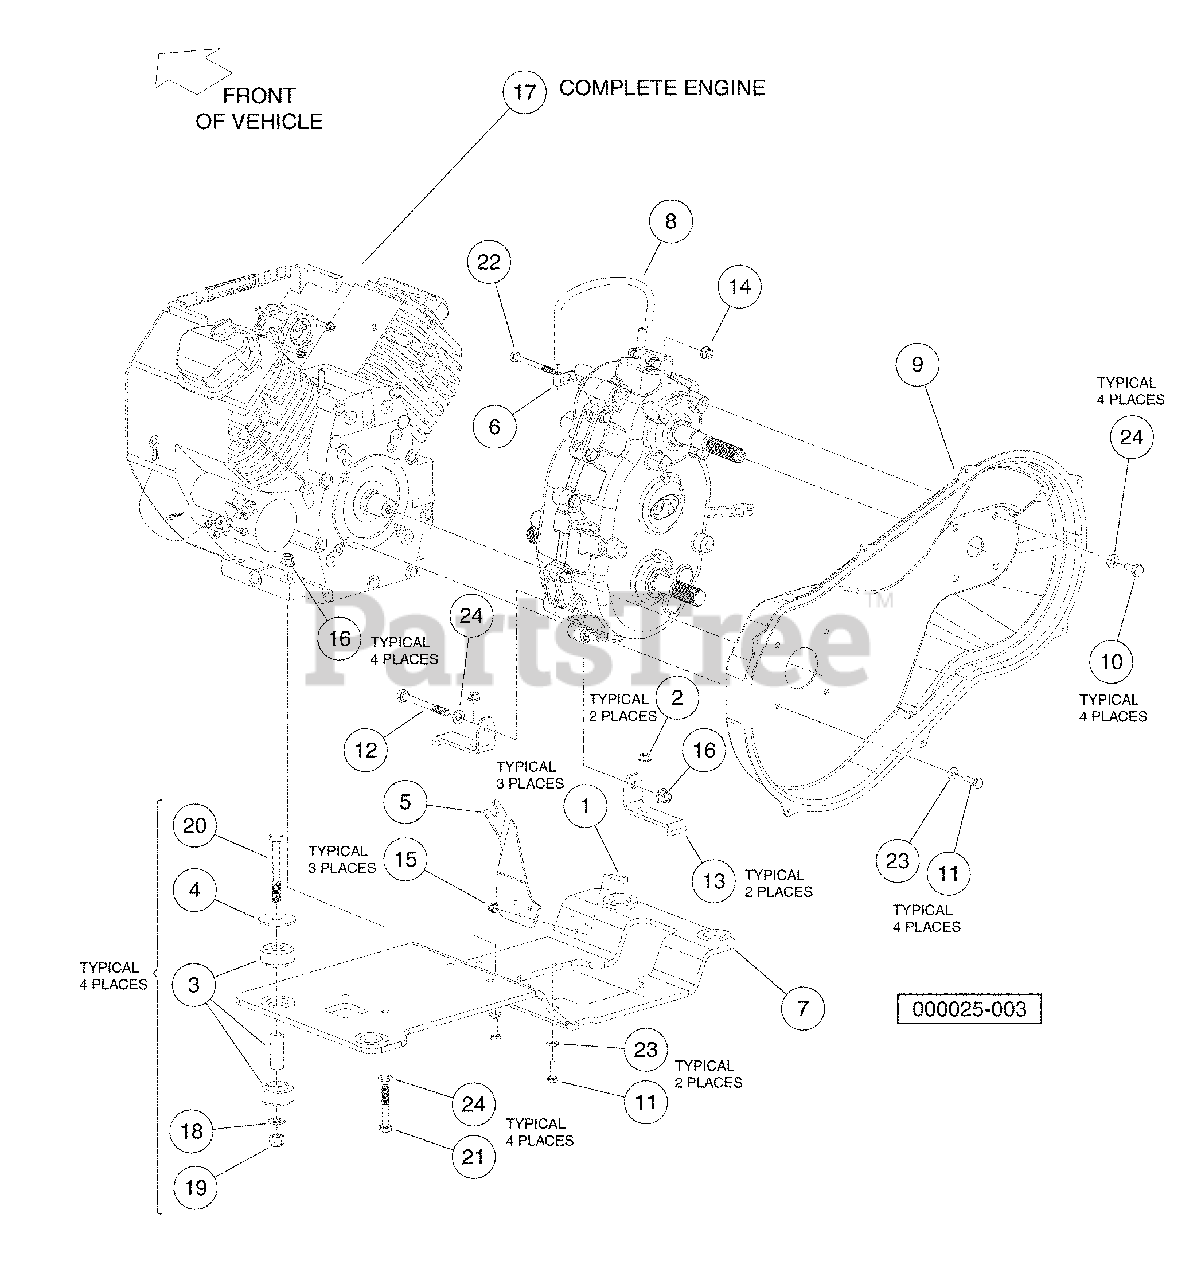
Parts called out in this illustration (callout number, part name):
1	Screw, M6-1.00 X 25mm Hex Cap
2	Nut,m8,all Metal Lock
3	Isolator Ring and Bushing
4	Washer, Snubbing, Ring N Bush
5	Bracket, FNR Trans Cable
6	P-Clamp, Insulated .312 In
7	Plate, Eng Mtg, Weld, Honda
8	Hose, Vent, Transmission
9	Cover, CVT Inner, Honda
10	Bolt, M10 X 1.5 X 20 Loctite
11	Bolt, M8 X 1.25 X 25 Loctite
12	Bolt, M10 X 1.5 X 100 Loctite
13	Bracket, Transmission Mounting
14	Lock Nut, Flg M8 X 1.25 Nylon
15	Nut Flg, M6 X 1.0 Nylon
16	Nut Flg M10 X 1.5 Nylon
17	Engine, Honda, No Acr
18	Washer, M12 Hard
19	Locknut, M12x1.75 Nylon Insert
20	Bolt, M12 X 1.75 X 90
21	Bolt, M10 X 1.5 X 60
22	Bolt, M8 X 1.25 X 80
23	Washer, M8 Hard
24	Washer, M10 Hard
